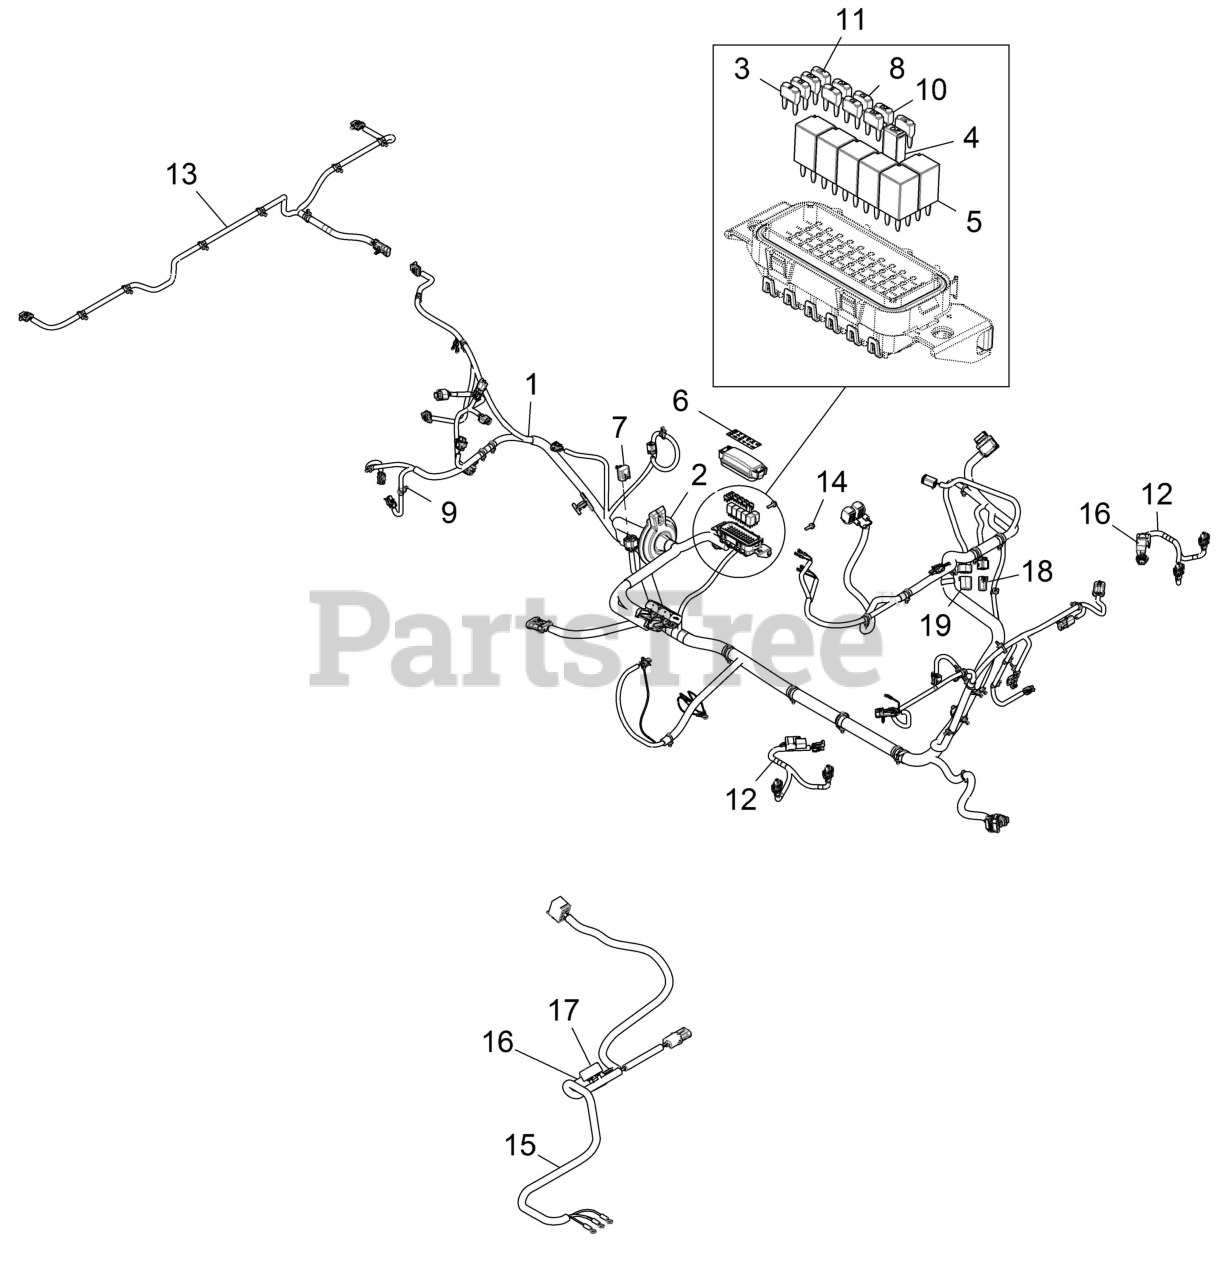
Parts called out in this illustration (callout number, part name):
1	HARNESS-CHASSIS,570,EPS
2	GROMMET-CHASSIS HARNESS
3	FUSE-5A,MINI BLADE
4	BREAKER-CIRCUIT,20 AMP
5	RELAY-SPST,SERIES 303,SEALED
6	DECAL, RELAY/FUSE BLOCK
7	COVER-DIAGNOSTIC,W/CLIP
8	FUSE,IGN.10 AMP,(10)
9	CLIP-ROUTING
10	FUSE,PARK,20 AMP,(10)
11	FUSE,MAIN,30 AMP,(10)
12	HARNESS-HEADLIGHT,ARIENS
13	HARNESS-BOX-ARIENS SPLY
14	SCR-M6X1.0X20,HXHD,FLG,TDFM,BL
15	HARNESS-BOX,LIFT
16	RELAY-MICRO,SPST,35A,SEALED
17	BREAKER-CIRCUIT,20 AMP,SEALED
18	CONNECTOR-CAP,EPS SIGNAL
19	CONNECTOR-CAP,EPS POWER
